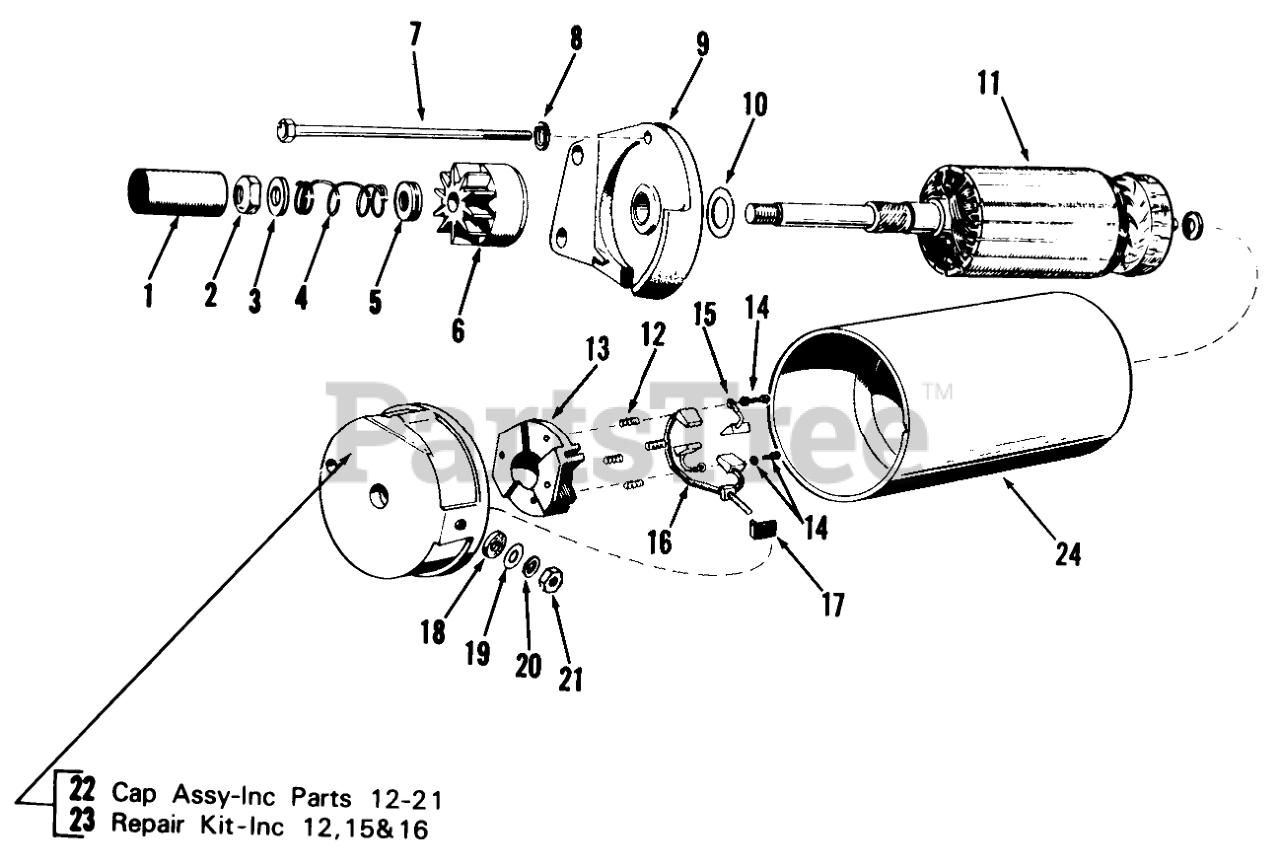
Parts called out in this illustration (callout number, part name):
1	Dust Cover
2	Stop Nut
3	Washer-Stop Nut
4	Spring-Anti Drift
5	Dust Cover Spacer
6	Drive Assembly
7	Tie Bolt
8	Lock Washer
9	Cap Assy-Drive End
10	Armature Thrust Washer
11	Armature
22	Cap Assy-Inc Parts 12-21
23	Repair Kit Inc 12, 15 & 16
